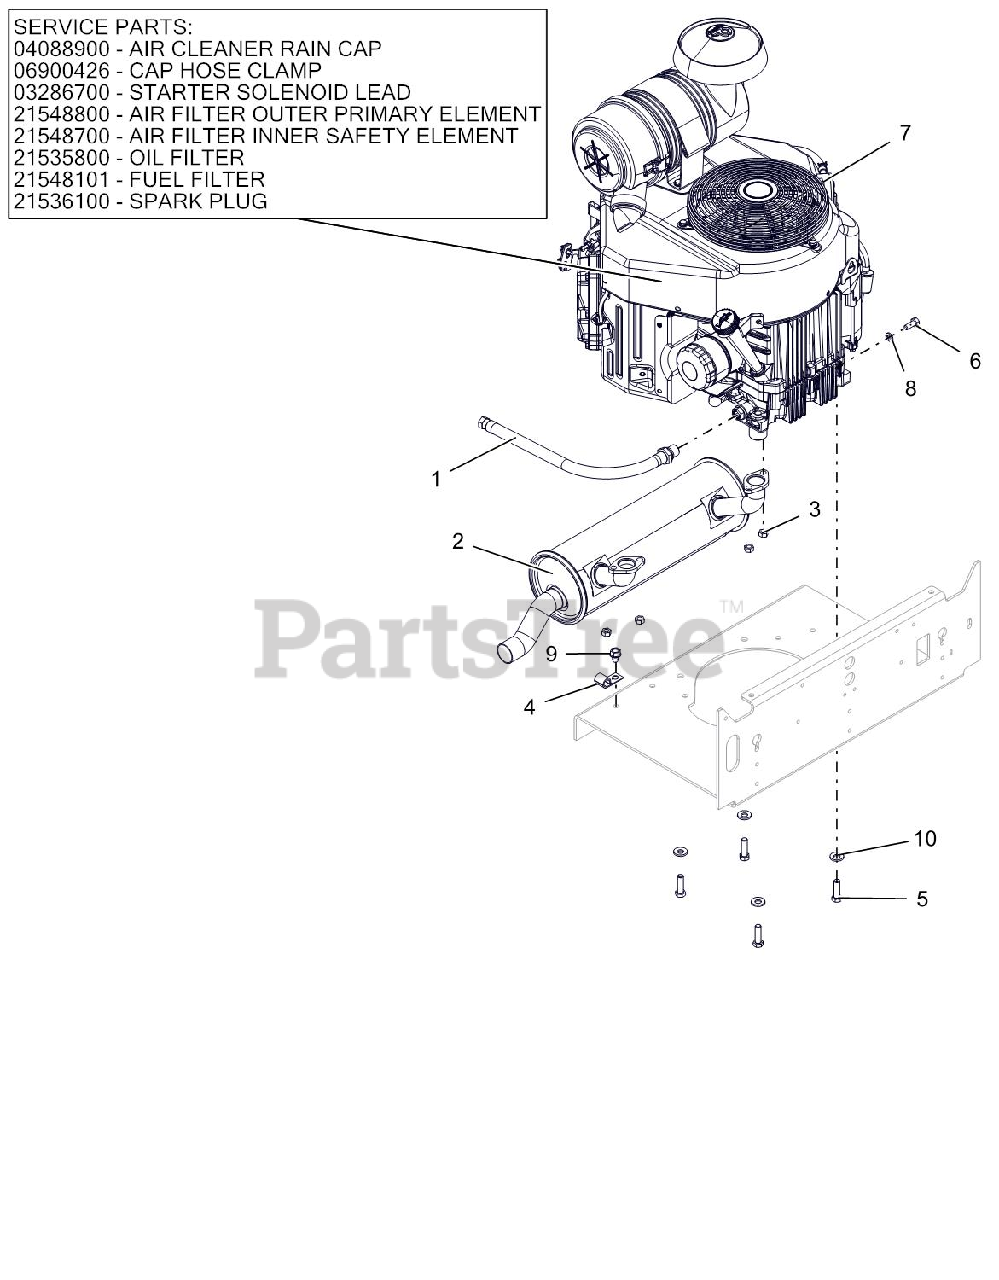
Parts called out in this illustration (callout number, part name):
1	HOSE, OIL DRAIN
2	MUFFLER, KAW FX691/730
3	NUT-LK-TOP M8-1.25 YWZC
5	BLT-HEX.38-16X1.25 G5YZ NYTORQ
6	@BLT-HEX M8-1.25X20 YWZC
7	FILTER,OIL - KAW
7	PLUG, SPARK
7	LEAD - STARTER SOLENOID
7	CAP, KAW 11065-7025
7	CLAMP, HOSE #36 SS 1.813-2.75
7	FILTER, OUTER
7	FILTER, INNER - KAW
7	ENGINE, KAWASAKI FX691
7	FUEL FILTER-KAWASAKI FR
8	@WSHR-LK .31X.078 REG YWZC
9	@SCR-TAP .38-16X.50 HWH TR YWZ
10	WASHER, 3/8" SPRING DISC
